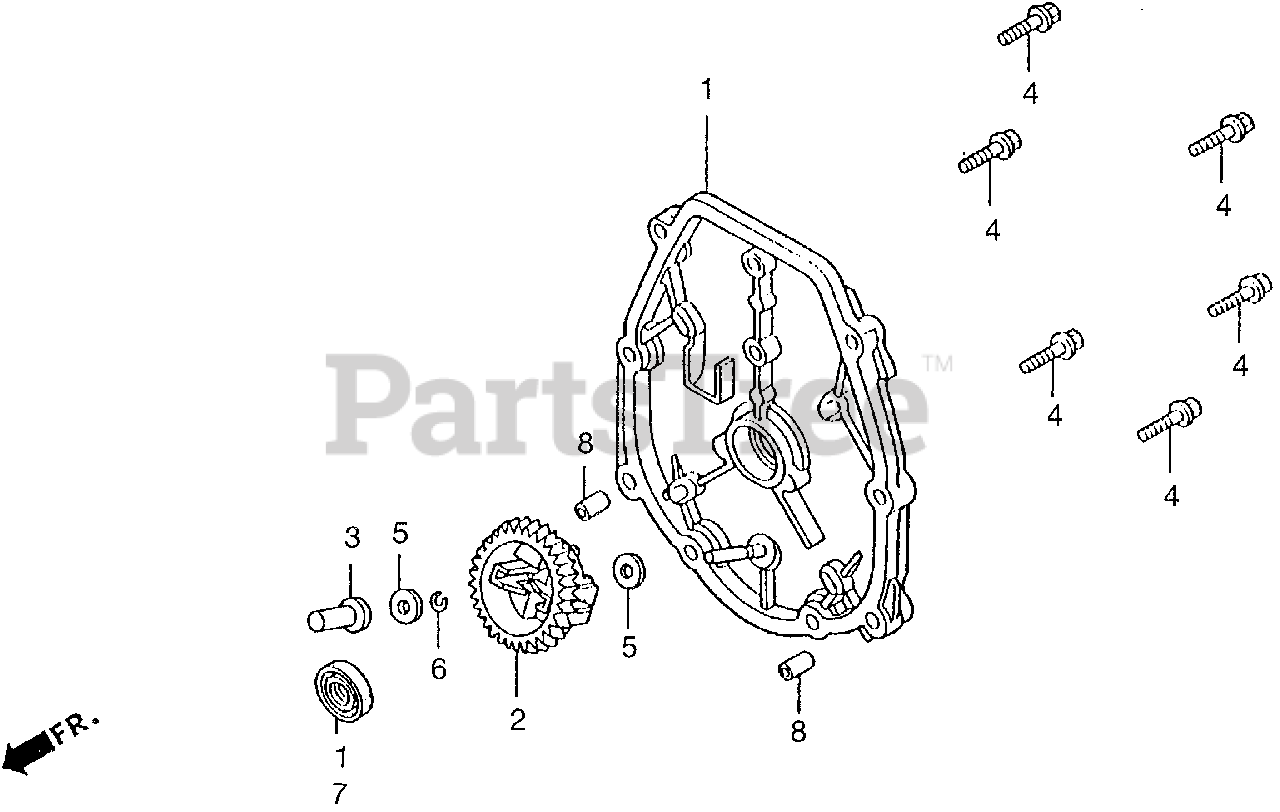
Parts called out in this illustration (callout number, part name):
1	COVER, CRANKCASE SIDE
2	GOVERNOR ASSY.
3	SLIDER, GOVERNOR
4	BOLT, FLANGE (5X23)
5	WASHER (4.2X13)
6	CLIP, GOVERNOR HOLDER
7	OIL SEAL (17X27X5) (KOYO)
8	PIN A, DOWEL (6X10)
